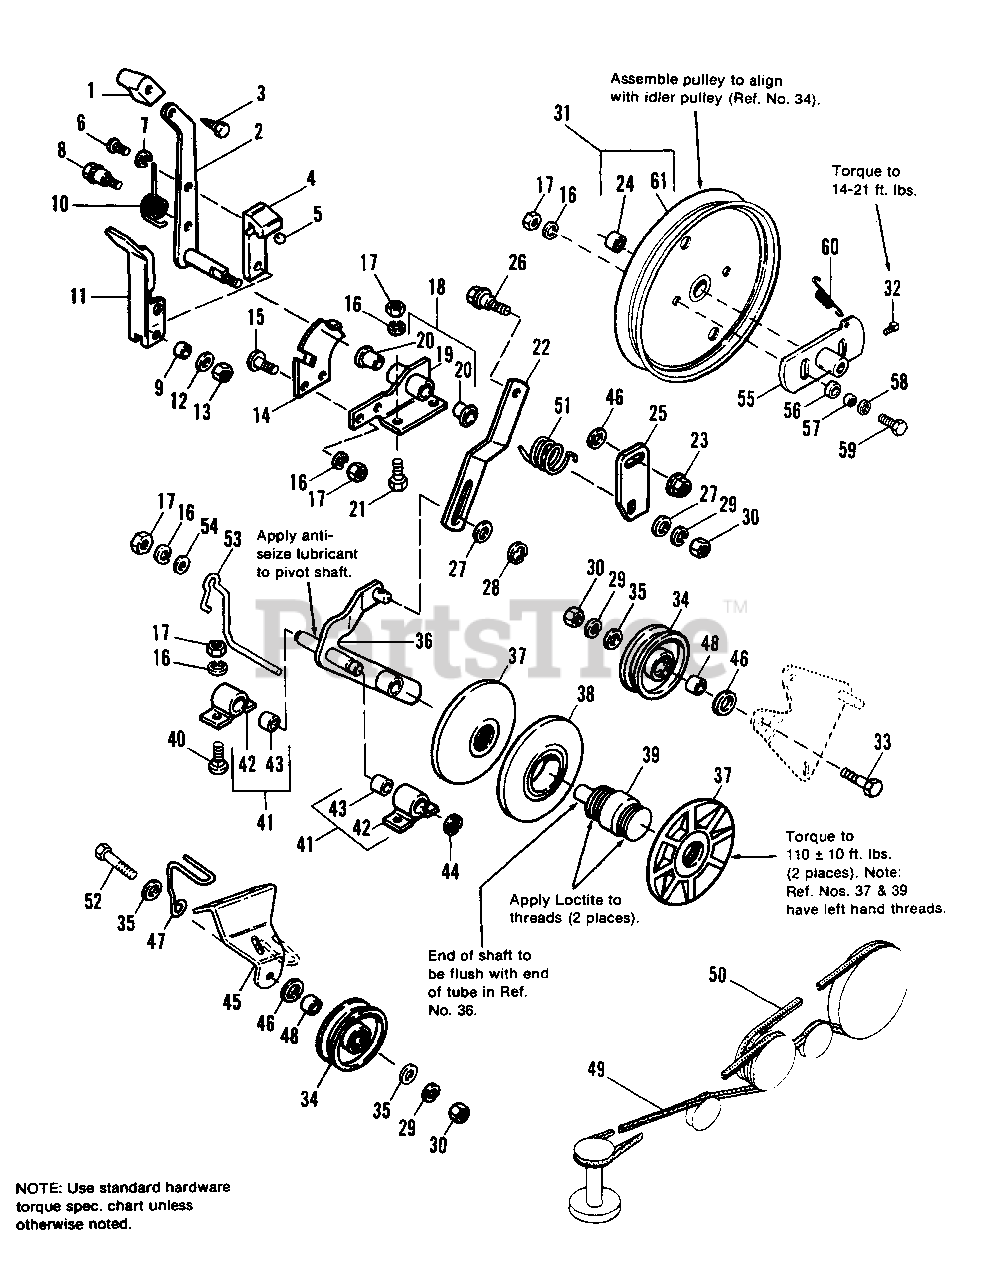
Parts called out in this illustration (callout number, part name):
2	CONTROL LEVER ASSY.
3	SCREW, Hex, Plastite 1/4-20 x 1
4	STOP, Clamp
5	BALL, Shift Handle
6	SCREW, Rd. Hd. Phil., 1/4-20 x 1/2
7	LOCKWASHER, 1/4
8	BOLT, Shoulder
12	WASHER, 1/4
13	LOCKNUT, Hex, 1/4-20
14	PLATE, Side
15	SCREW, Truss Hd., Slotted, 5/16-18 x 3/4
16	LOCKWASHER
17	NUT, Hex, 5/16-18
18	SUPPORT ASSY., w/Bushings (Incl. Ref. Nos. 19 & 20)
21	SCREW, Hex, 5/16-18 x 7/8
22	BAR, Push
23	LOCKNUT, Flange, Whiz, 3/8-16
25	PLATE, Lift
26	BOLT, Shoulder
27	WASHER, 3/8
29	LOCKWASHER, 3/8
30	NUT, Hex, 3/8-16
31	PULLEY ASSY., Transmission (Incl. Ref. No. 24 & 61)
33	SCREW, Hex, 3/8-16 x 1-1/2
34	PULLEY ASSY.
35	WASHER, 5/16
36	ARM ASSY., Swing
37	SHEAVE, Single
38	SHEAVE, Double w/Sleeve
39	HUB ASSY.
40	BOLT, Carriage, 5/16-18 x 3/4
41	PIVOT ASSY., Variator w/Bushing (Incl. Ref. Nos. 42 & 43)
44	E-RING
45	SUPPORT, Idler
46	WASHER
47	BELT STOP, Idler
49	BELT, Primary Variator
50	BELT, Secondary Variator
51	SPRING, Torsion
52	SCREW, Hex, 3/8-16 x 1-3/4
54	WASHER, 3/8
55	HUB ASSY., Drive
59	CAPSCREW, 5/16-18 x 1
